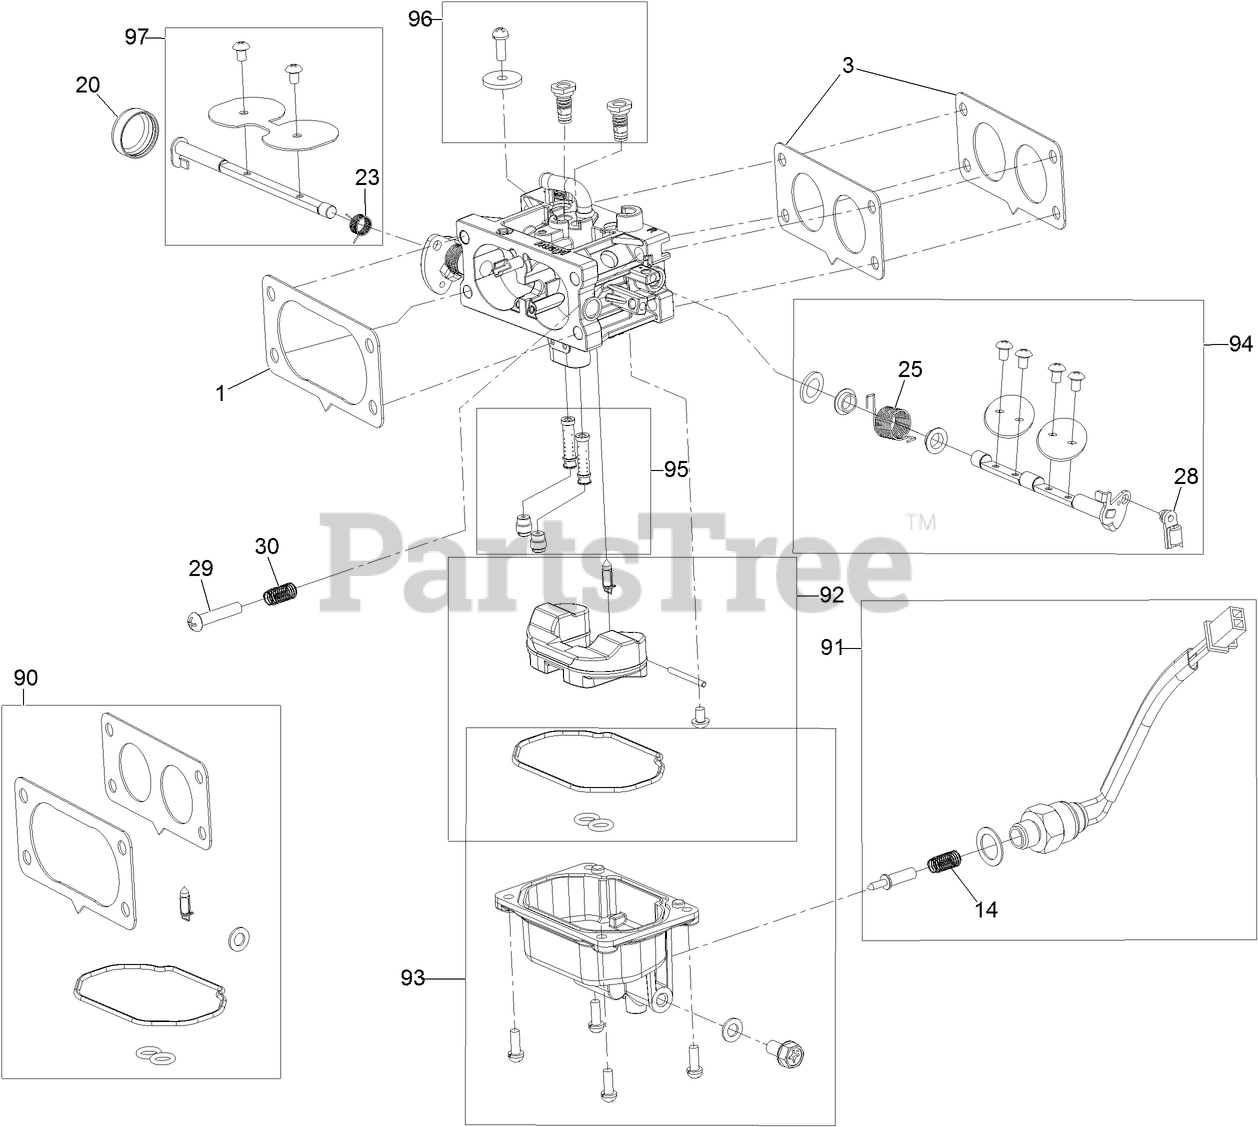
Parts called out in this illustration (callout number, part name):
1	GASKET-CARBURETOR
3	GASKET-CARBURETOR
14	SPRING
20	COVER-SHAFT, CHOKE
23	SPRING
25	SPRING
28	CLAMP-LOCK
29	SCREW-PPH
30	SPRING
90	CARBURETOR REPAIR KIT
91	SOLENOID KIT
92	FLOAT KIT
93	BOWL KIT
94	THROTTLE SHAFT KIT
95	NOZZLE AND JET KIT
96	IDLE JET KIT
97	CHOKE SHAFT KIT
